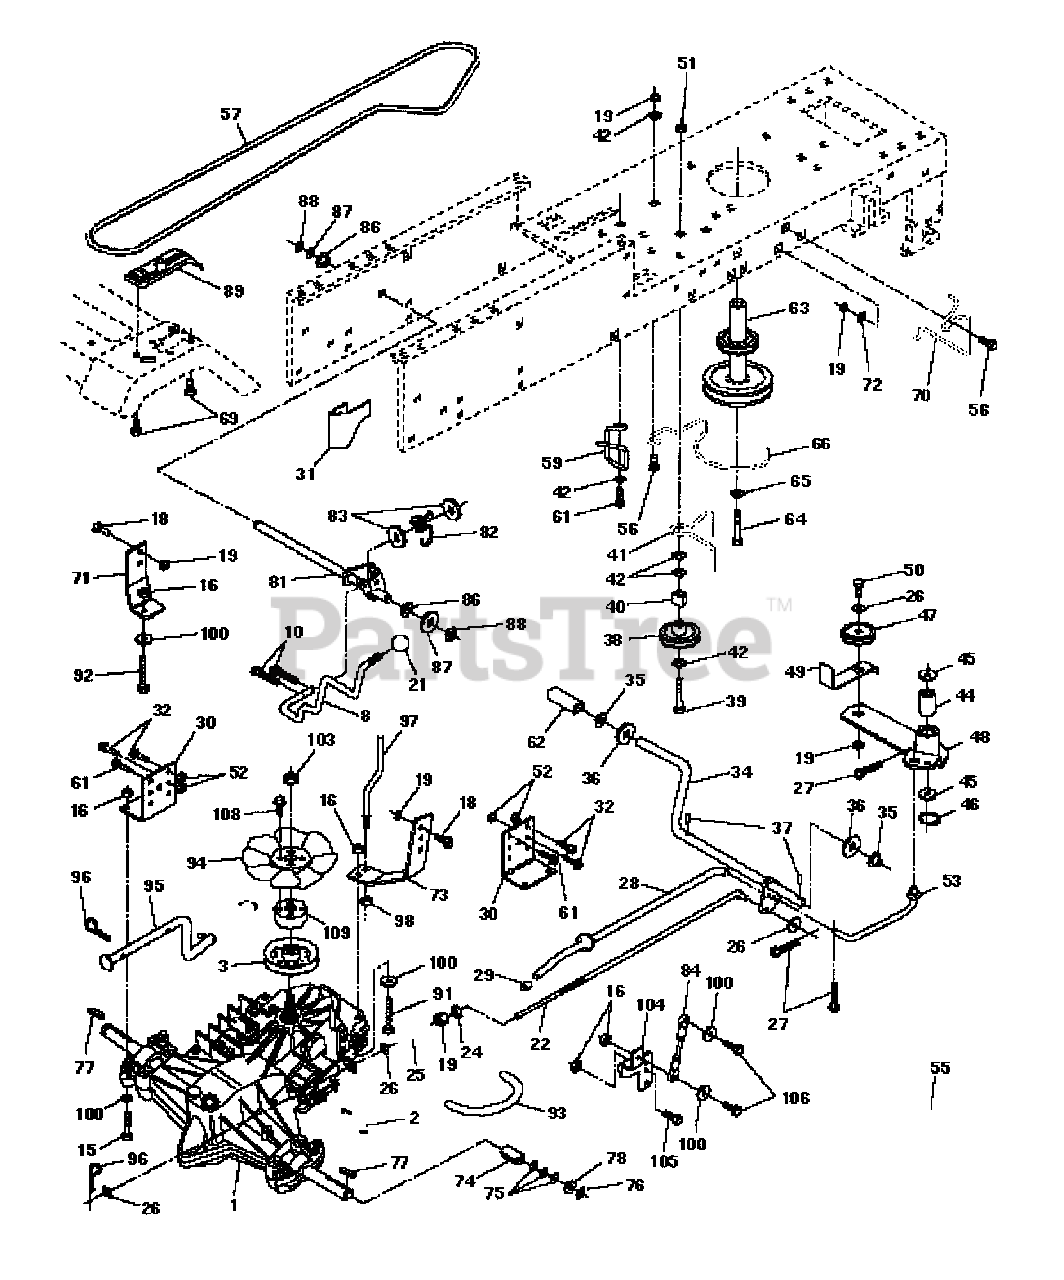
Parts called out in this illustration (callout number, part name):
1	Transaxle Assembly
2	Spring, Return, Brake
3	Pulley, Transaxle
8	Rod Shift Hydro LT
10	Pin Cotter 1/8 x 1 CAD
15	Bolt Fin Hex 5/16-18 Unc
16	Nut Lock Hex W/Ins 5/16-18 Unc P
18	Bolt Fin Hex 3/8-16 Unc x 1 Gr. 5
19	Nut Lock Hex W/Wsh 3/8-16 Unc
21	Knob 1/2-13
22	Rod, Brake Hydro
24	Nut
25	Spring, Brake Rod
26	Washer
27	Pin Cotter 1/8 x 3/4 CAD.
28	Rod, Parking Brake
29	Cap, Parking Brake
30	Bracket, Transaxle
31	Keeper Belt Lh
32	Bolt Hex Hd 5/16-18 Unc x 3/4
34	Shaft, Foot Pedal
35	Bearing, Nylon
37	Pin, Roll
38	Pulley, Idler, Flat
40	Spacer, Split
41	Keeper, Belt Retainer
42	Washer 13/32 x 13/16 x 12 Gauge
44	Bearing, Nylon
45	Washer, Hardened
46	Ring, Klip
47	Pulley, Idler, V-Groove
48	Bellcrank Assembly
49	Retainer, Belt
50	Bolt
51	Nut Crownlock 3/8-16
52	Nut Crownlock 5/16-18
53	Link, Clutch
55	Spring, Return, Clutch
56	Bolt Fin Hex 3/8-16 Unc x 1-1/4
57	V-Belt, Ground Drive
59	Keeper, Center Span
61	Screw Thdrol. 3/8-16 x 3/4 Ty. TT
62	Cover, Pedal
63	Pulley, Engine
64	Bolt, Hex
65	Washer
66	Keeper Belt Engine
70	Keeper Belt Engine
71	Strap Torque Lh Hydro 500 18"
72	Washer 13/32 x 1-1/4 x 12 Gauge
73	Strap Torque Rh Hydro 500 18"
74	Spacer, Split
75	Washer 25/32 x 1-1/4 x 16 Gauge
77	Key, Square
78	Washer 25/32 x 1-5/8 x 16 Gauge
81	Shaft Asm. Cross Hydro 500
82	Spring Torsion T/A
83	Washer 17/32 x 3/4 x 16 Ga.
84	Rod, Tie Hydro Sph Ball 500
86	Bushing Rod Strig. 629/632 ID
87	Washer 21/32 x 1-1/4 x 16 Ga.
88	Ring Klip #5304-62
89	Console, Shift
91	Bolt Fin Hex 5/16-18 x 2-1/4
92	Bolt Fin Hex 5/6-18 Unc x 1-1/2
93	Line Fuel Hydro 4"
94	Fan, Hydro 7"
95	Control Asm. Bypass Hydro
96	Retainer Spring 1" Zinc/Cad
97	Keeper Belt Rh Hydro 500
98	Nut Keps Hex 3/8-16 Unc
100	Washer 11/32 x 3/4 x 16 Ga.
103	Nut Nylon Insert 1/2-20 Unf.
104	Arm, Control Pump
105	Screw Cap Hex 5/16 x 18 x 1
106	Bolt Fin Hex 5/16-18 Unc x 1-1/4
108	Screw Hex Wh Hd #10-24 x 1-5/8
109	Adaptor Fan/Hydro Lt Hyd Alum
